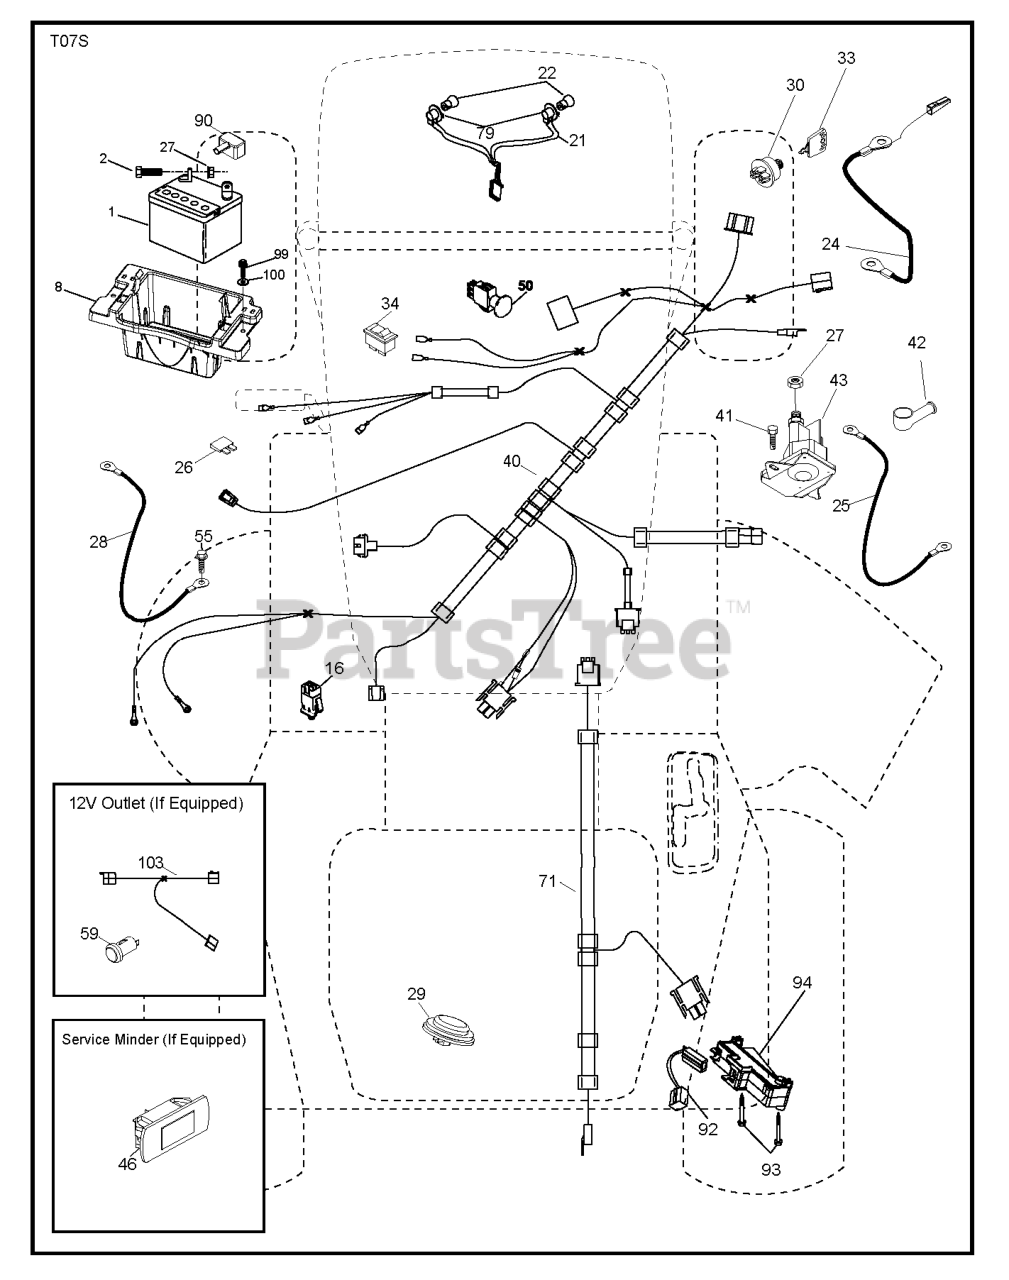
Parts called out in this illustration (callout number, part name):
1	Battery, Dry 30 Amp
2	BOLT.HEX.1/4.X.3/4.DICHROMATE
8	BOX.BATTERY.MOUNT.FRONT.LT
16	SWITCH INTERLOOK PUSH-IN
21	HARNESS.LIGHT W/4152J BULBS
24	CABLE.FRBATT.W/WIRE.8GA.8
25	CABLE.STARTER.6G.BL/RED.17.5
26	FUSE 20AMP
27	NUT
28	CABLE.GROUND.21"BLK.8GA.90T
29	SWITCH.SEAT.DELTA.OPC.
30	SWITCH.IGN.DELTA.W.LGH.ROS
33	KEY.CHAIN.BLISTER.PACK.GEN.INT
40	HARNESS.IGN.DASH.HUQ/P
41	SCREW
42	TERMINAL COVER
43	SOLENOID.W/BRASS.PLUNGER
46	RP.GUAGE.SRVCMNDR.HRMTR.
50	RP.PTO.SWITCH.8 TERMINAL.BLACK
55	SCREW 5/16"
71	HARNESS-CHASSIS SUB
79	BULB HOLDER ASM.
90	COVER.TERMINAL.BATTERY
91	STRAP.BATTERY.MOUNT.FRONT(2 2)
92	HARNESS.PIGTAIL.CONSLE
93	SCREW.PLASTITE
94	MODULE.REVERSE.ROS
99	SCREW HEXWSHR 1/4-20X3/4
100	WASHER
103	HARNESS PIGTAIL 12V OUTLET
